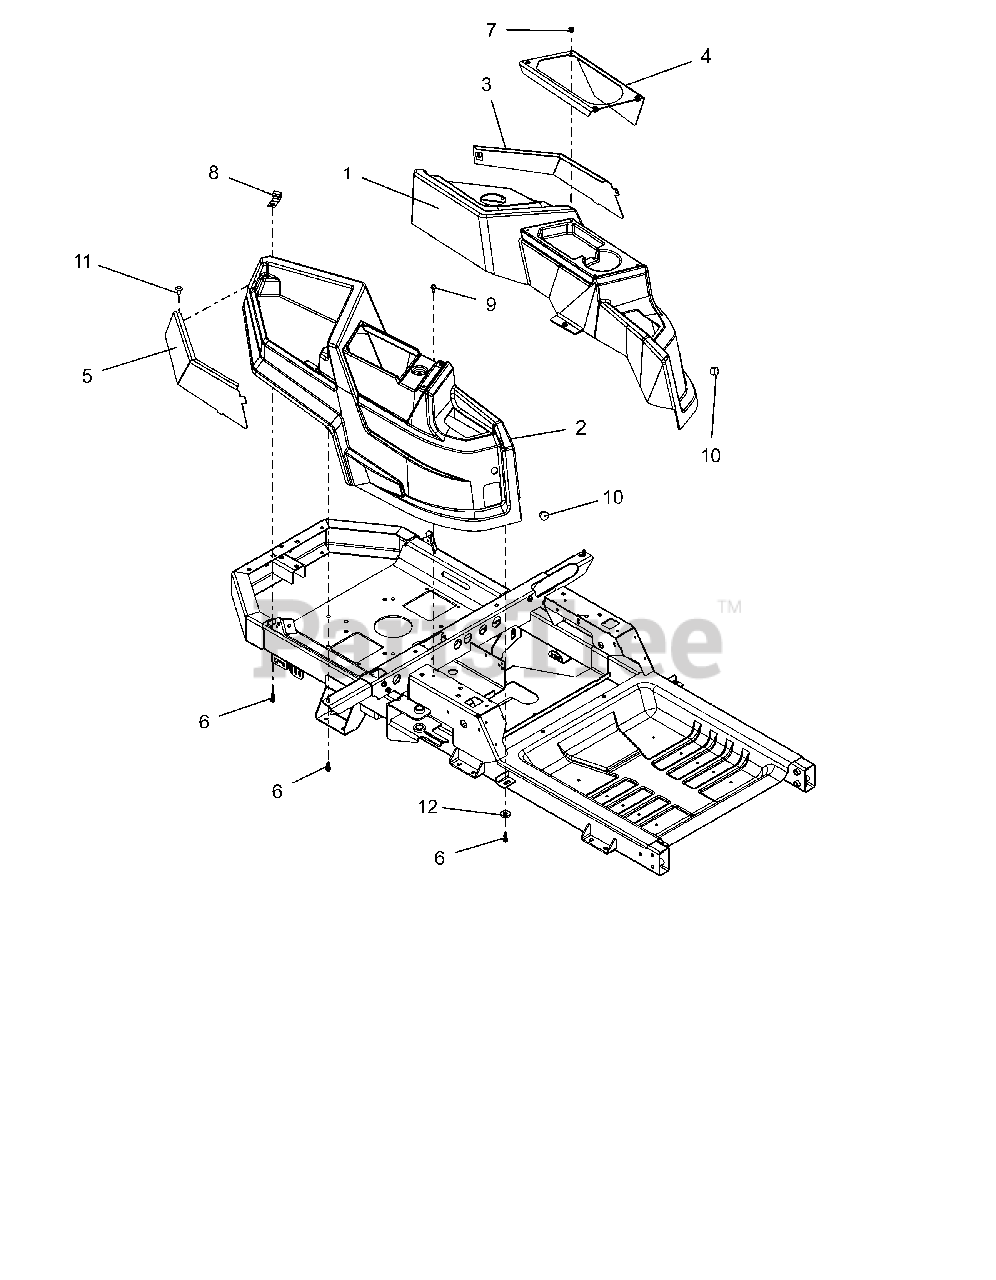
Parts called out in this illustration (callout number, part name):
1	FENDER, LH -ZOOM
2	FENDER, RH -ZOOM
3	WLDMT, FENDER BLOCKOFF XL -LH
4	PANEL, CUPHOLDER/STORAGE (LH)
5	WLDMT, FENDER BLOCKOFF-RH XL
6	SCR-.312X.75 #14H H/W/H H/L CZ
7	RIVET, PLASTIC .195 DIA.
9	SCR-TAP .25-20X.50 HWH ZCC
10	PLUG, HOLE .75 (BLACK)
11	XMAS TREE FASTNER-BLACK
12	WSHR, FLT .406X1.00X.188 ZCC
